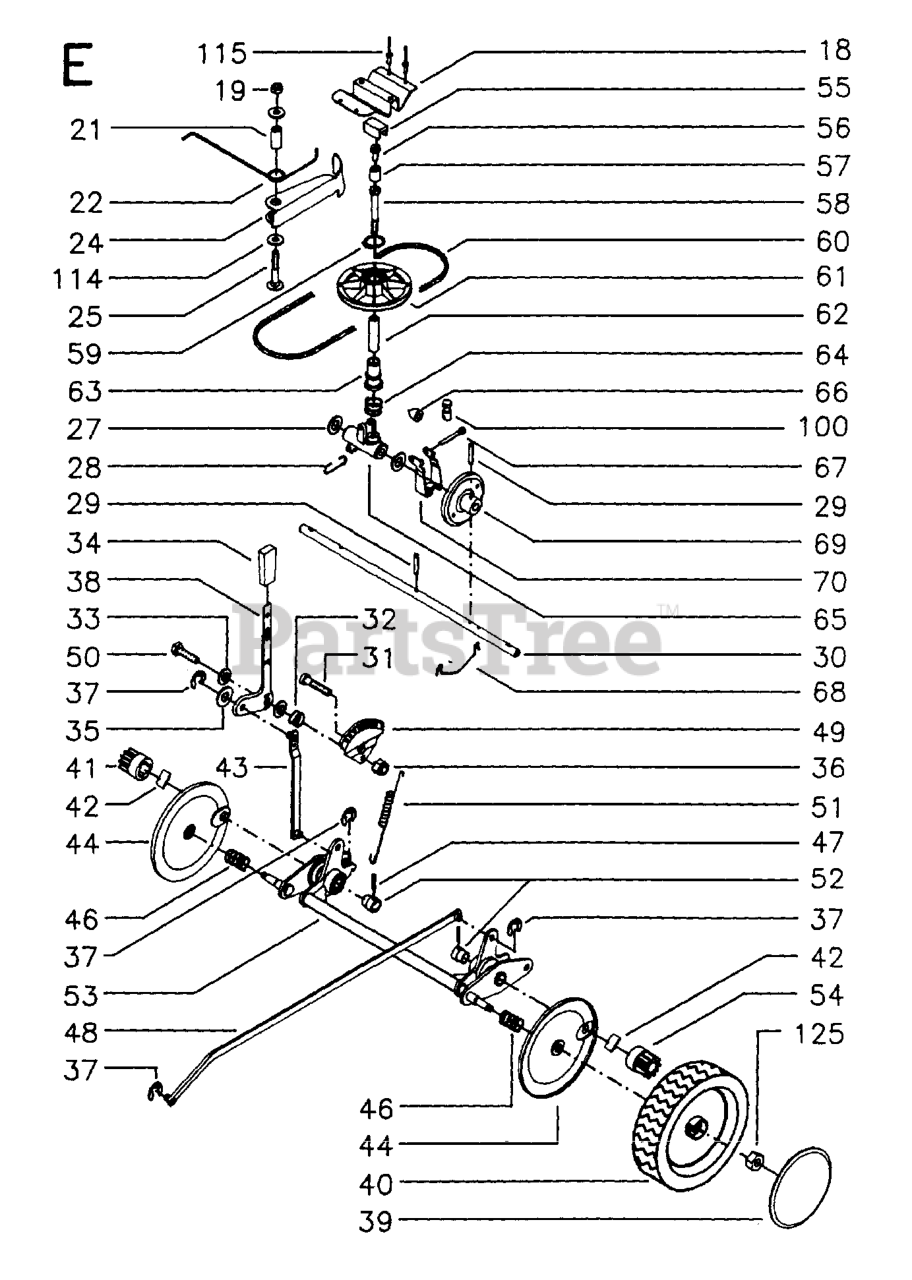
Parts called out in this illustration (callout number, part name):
19	LOCKNUT M6
27	WASHER
28	CLIPS
29	SPRING PIN 5X28
30	SHAFT
31	SCREW
39	WHEEL COVER
41	PINION, RIGHT
42	CARRIER
44	SHIELD
46	SPRING
49	INDEXPLATE
54	PINION, LEFT
55	SLIDE BEARING
56	SCREW
60	BELT
61	PULLEY
63	SLEEVE
65	HOLDER
68	HOLDER SPACER
69	WHEEL ASSY FRICTION
70	RAM
